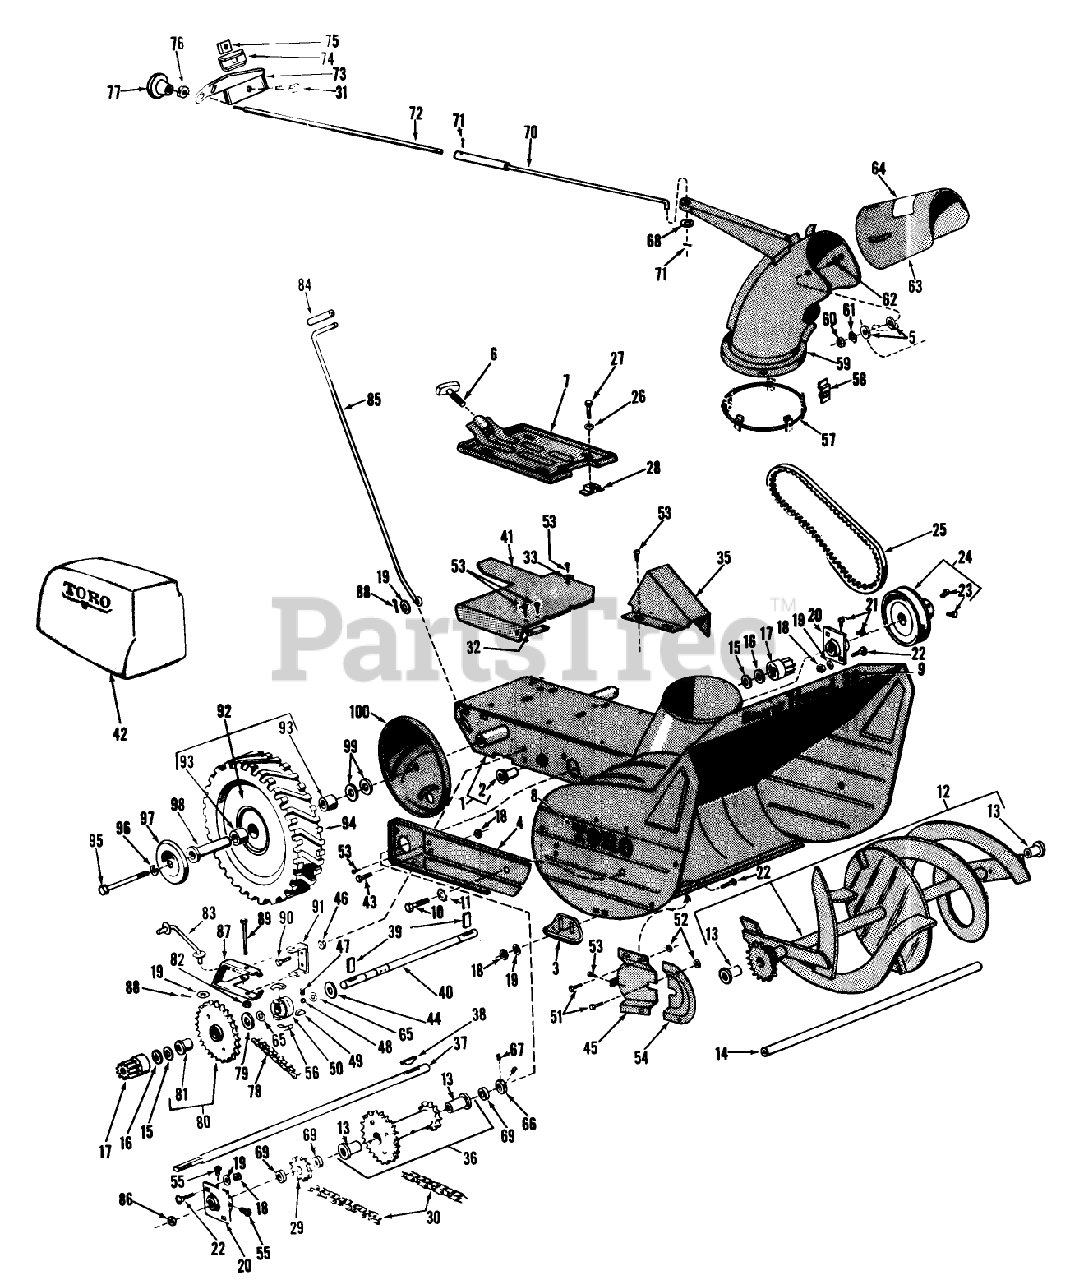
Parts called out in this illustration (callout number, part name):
1	Frame Incl. Ref. #72
2	BUSHING
3	Skid
4	Support-Bearing
5	Washer
6	Clamp Assy.
7	Adapter Plate
8	Decal
9	Decal
10	SCREW-HH
11	LOCKWASHER-PYRAMID
12	Rotor Incl. Ref. #44
13	Bushing
14	ROTOR SHAFT
15	Washer
16	Snap Ring
17	Pinion Kit
18	Nut
19	WASHER-FLAT
20	Bushing Flange Mounted
21	SCREW-SQH
22	Bolt
23	SCREW-SET, HSH
24	Pulley
26	WASHER-PLAIN
27	SCREW-HH
29	Sprocket
30	Chain
31	Clamp Assembly
32	Chain Guide
33	Washer
35	Shroud Belt
36	Sprocket (Incl. Ref. 7)
37	Drive Shaft
38	KEY-WOODRUFF
39	RATCHET DOG
40	Drive Shaft
41	Chain Guard
42	Engine Cover Assy.
43	SCREW-HH
44	Washer
45	Guard, Chain
46	Locknut
47	Spring
48	BALL-STEEL
49	KEY-WOODRUFF
50	Sliding Jaw
51	SCREW-SHWH
52	NUT-LOCK, NI
53	Screw Self Tapping
54	Guard-Rotor Chain
55	SCREW-SET, HSH
57	Garter Spring
59	Chute
60	Nut
61	WASHER-FLAT
62	SCREW-PPH
63	Deflector
64	Decal
65	5/8X039 EX HD RING
66	Collar
67	SCREW-HSH
68	WASHER-FLAT
69	COSHAFT SPACER
70	Rod-Chute
71	PIN-COTTER
72	Control Rod Upper Chute
73	Bracket-Control
74	Strap, Clamp
75	Retaining Nut
76	Grommet
78	Chain
79	Thrust Washer
80	Drive Sprocket Assembly
81	BUSHING-FLANGE
82	Nut
83	Link Shift
85	Control Rod Traction
86	NUT-LOCK, NI
87	Fork Shift
88	PIN-COTTER
89	SCREW-HH
90	SCREW-HH
91	Pivot Support
92	Wheel Incl. Ref. #97
93	BUSHING
95	SCREW-HH
96	WASHER-LOCK
97	Hub Cap
98	Spindle Wheel
99	WASHER
100	Wheel Cover
